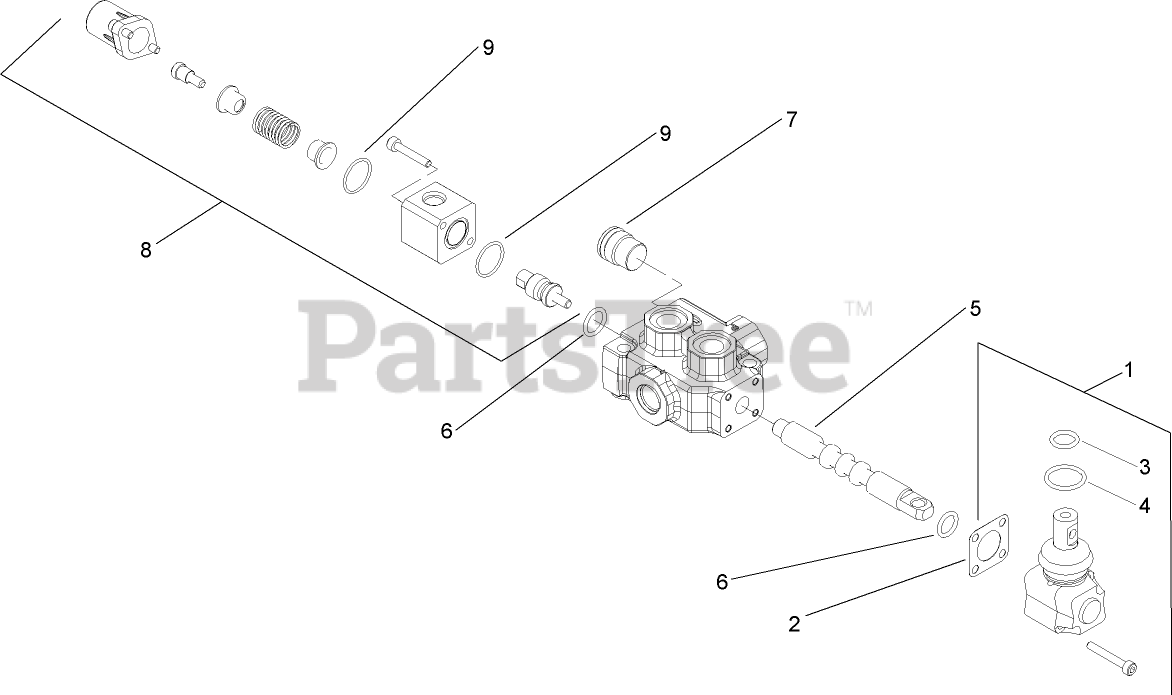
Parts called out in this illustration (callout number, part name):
1	LEVER KIT
2	GASKET
3	SEAL-LEVER
4	SEAL-LEVER
5	SPOOL-VALVE
6	SEAL-VALVE
7	PLUG-CAVITY, RELIEF
8	END CAP SPRING KIT
9	SEAL-CAP, END
